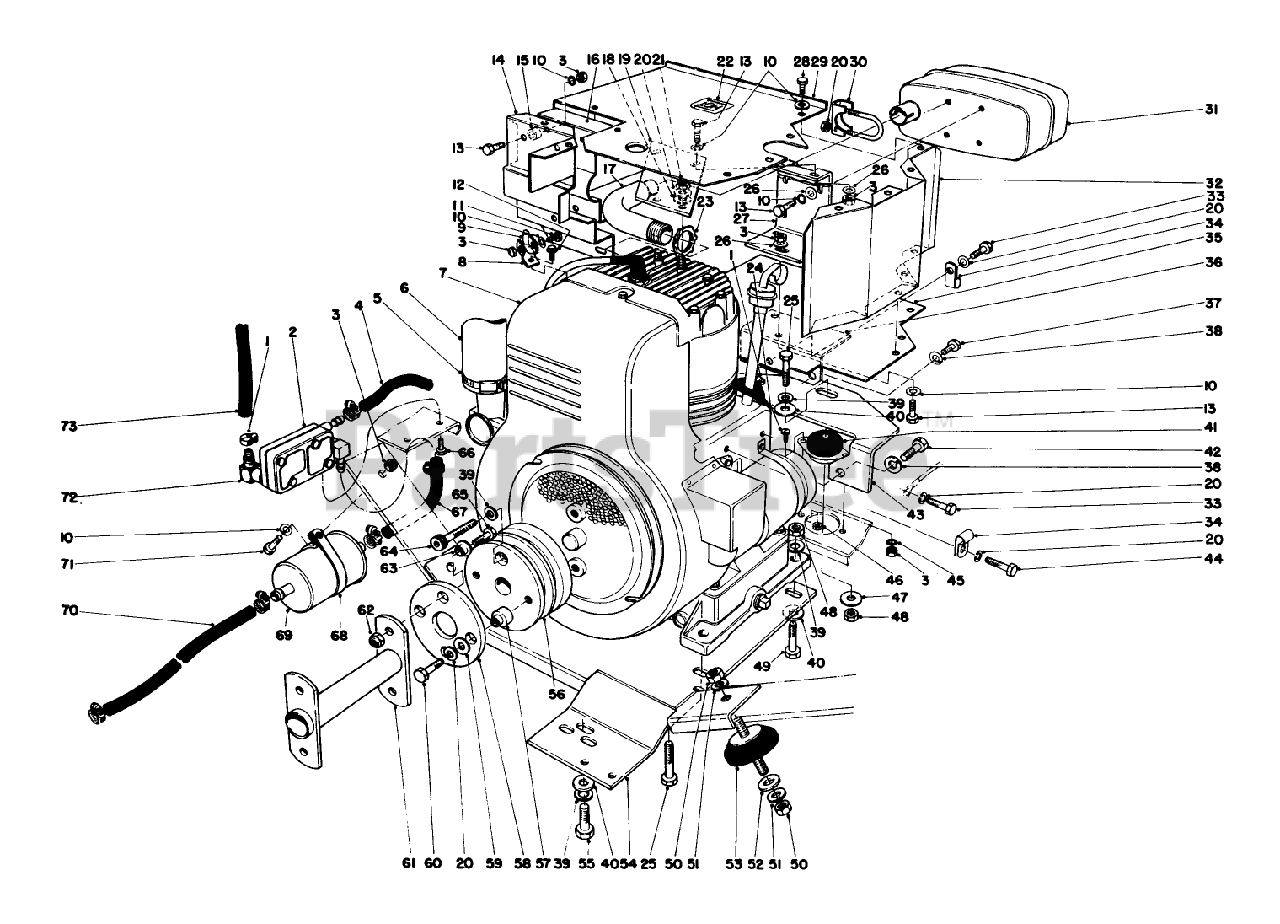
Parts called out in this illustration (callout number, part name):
1	CLAMP-HOSE
2	FUEL PUMP
3	NUT-HEX
4	PULSE LINE
5	CLAMP-HOSE
6	AIR CLEANER HOSE
7	Engine
8	BODEN CLIP BRKT
9	CLAMP-BODEN
10	WASHER-LOCK
11	SCREW
12	SCREW
13	SCREW-HH
14	REAR SHIELD WA B
15	SPACER HEAT SHIELD
16	Shield Exhaust
17	EXHAUST PIPE
18	WASHER-PLAIN
19	MUFFLER BRACKET B
20	Lockwasher
21	NUT-HEX
22	Decal-Hot
23	Locknut
24	10-24 X 5/8 PAN HD MS
25	SCREW-HH
26	WASHER-FLAT
27	MUFFLER BRKT B
28	SCREW THD 1/4 20 5/8
29	Top Heat Shield
30	MUFFLER CLAMP
32	LH SIDE HT SHIELD B
33	SCREW-HH
35	Bottom Heat Shield
36	Bracket Heat Shield
37	SCREW-HH
38	WASHER-LOCK
39	WASHER-LOCK
40	WASHER-FLAT
41	RUBBER MOUNT
42	SCREW-HH
43	REAR ENGINE MT B
44	SCREW-HH
45	WASHER-LOCK
46	NUT-LOCK, NI
47	WASHER
48	NUT-HEX
49	SCREW-HH
50	NUT-HEX
51	WASHER-LOCK
52	WASHER-FLAT
53	RUBBER MOUNT
54	ENGINE BASE WA
55	SCREW-HH
56	ENGINE PULLEY BO
57	SPACER-RUBBER COUPLNG
58	COUPLING-RUBBER
59	WASHER-FLAT
60	SCREW-HH
61	DRIVE COUPLING WA B
62	NUT-HEX
63	SPACER-COUPLING
64	SCREW-HSH
65	SCREW-HH
66	Screw-Outlet
67	HOSE-FUEL
68	1.875 ID HOSE CLAMP
69	FiIter Gas
70	HOSE-FUEL
71	SCREW-HH
72	FITTING
73	FUEL LINE
